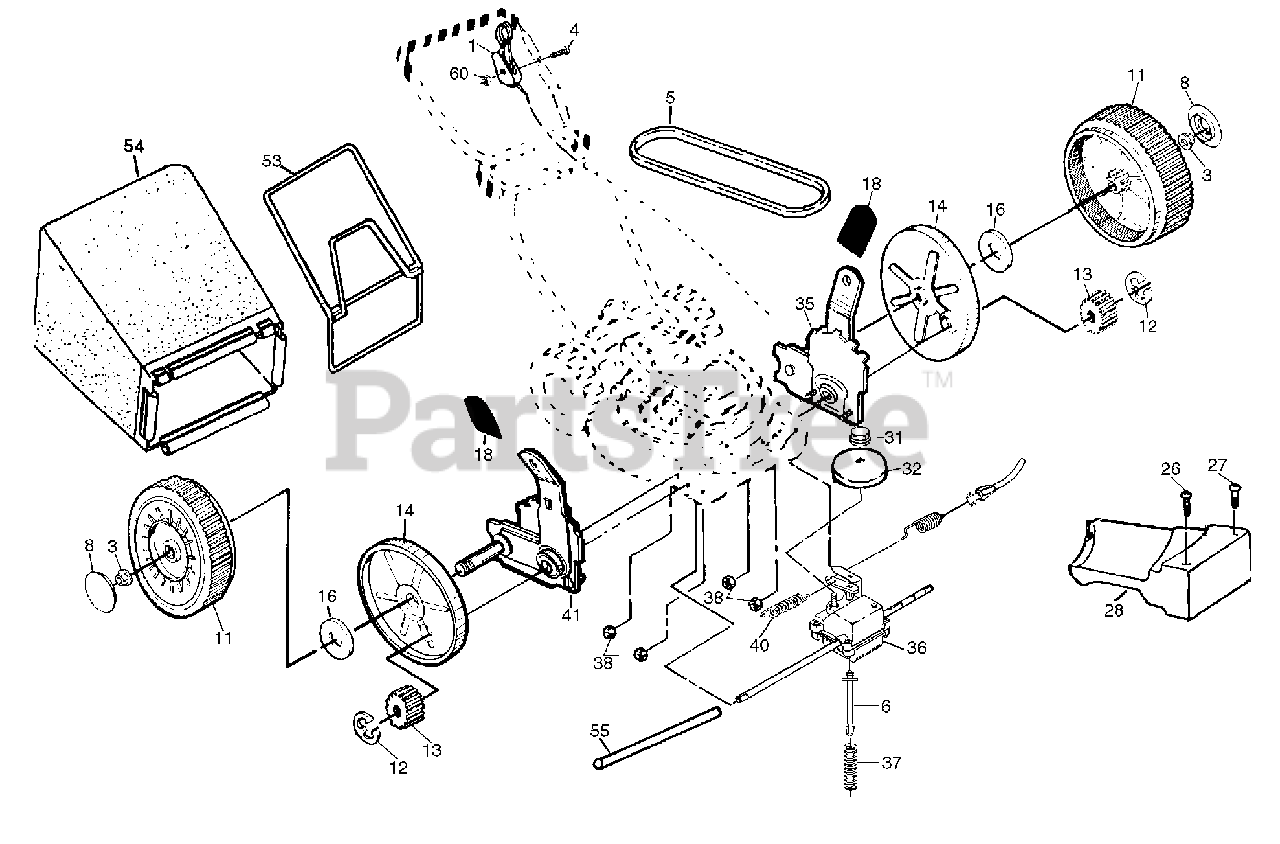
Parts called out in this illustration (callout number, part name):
1	Tapping Screw 1/4-20 x 1-1/4
2	Engagement Bracket
3	Shifter
4	Seal
6	Gear Case Halves Kit
7	Bearing
8	Worm Shaft
9	Drive Shaft
10	Hardened Washer
11	Clutch Yoke
12	Bushing
13	Plug
14	Helical Gear
15	Clutch Jaw
17	E-Ring
18	Hi-Pro Key
19	Spring Bracket
